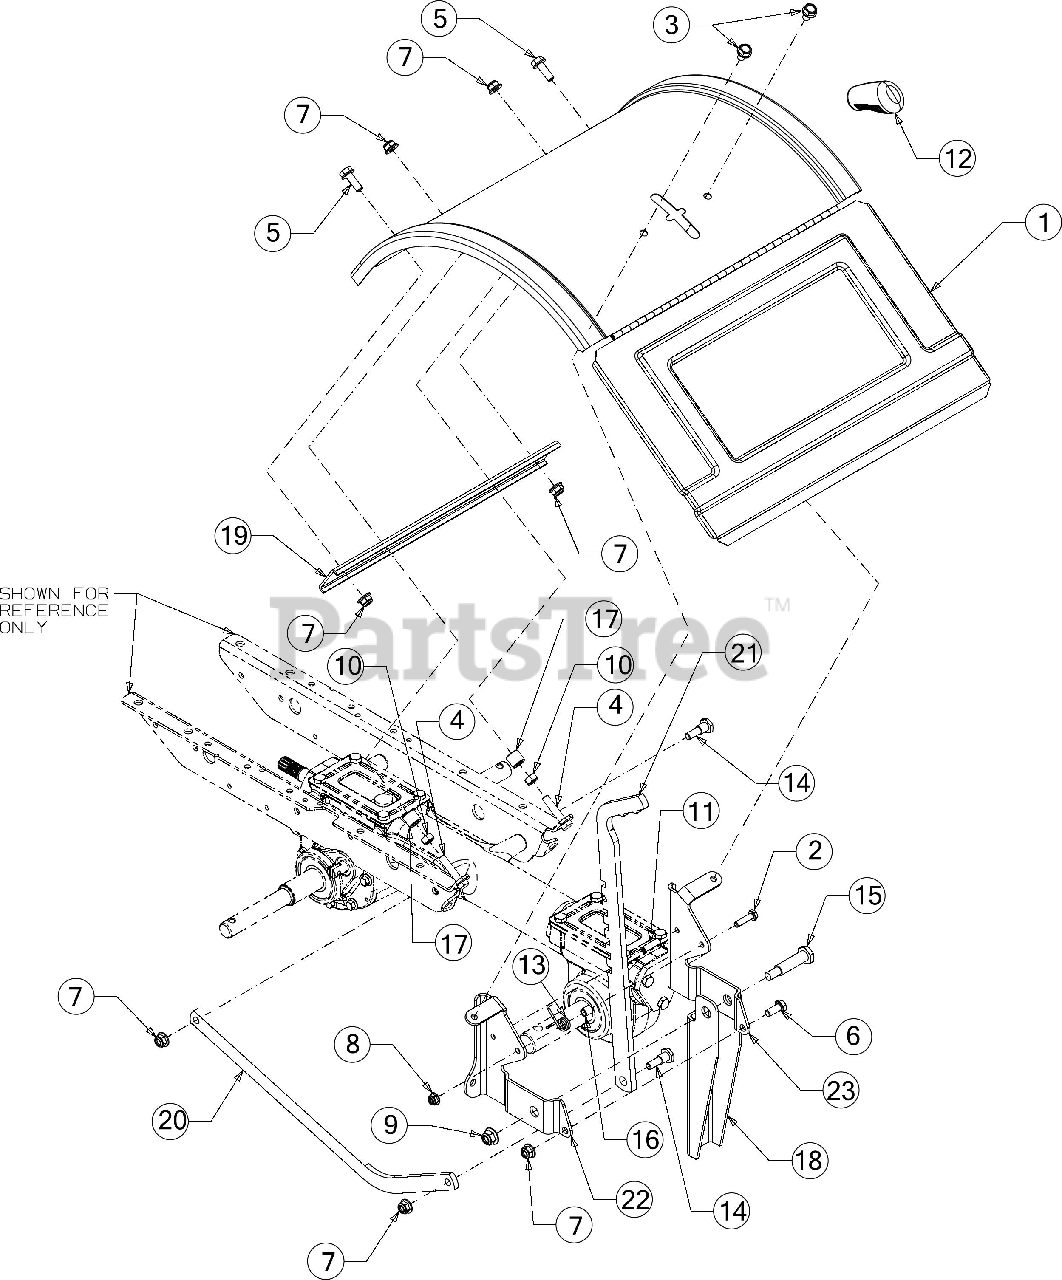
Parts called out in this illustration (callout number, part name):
1	TINE SHIELD ASSEMBLY
2	SCREW 1/4-20 X1.00 GR5
3	SCREW 5/16-18 X .625
4	SCREW 5/16-18 X 1.5 LG
5	SCREW 5/16-18 X .875 GR5
6	SCREW 5/16-18 X .75 GR5
7	FLANGE LOCK NUT 5/16-18
8	FLANGE LOCK NUT
10	HEX NUT
11	SPRING PIN 1/4 X 1.00
13	TORSION SPRING
14	SHOULDER SCREW
15	SHOULDER BOLT .498 X 1.635:3/8-16
16	ROUND SPACER
17	SPACER .335 X .625 X .560
18	REVERSE STOP ARM
19	SUPPORT BRACKET
20	DEPTH DRAG BAR
22	TAIL BRACKET (LH)
23	TAIL BRACKET (RH)
